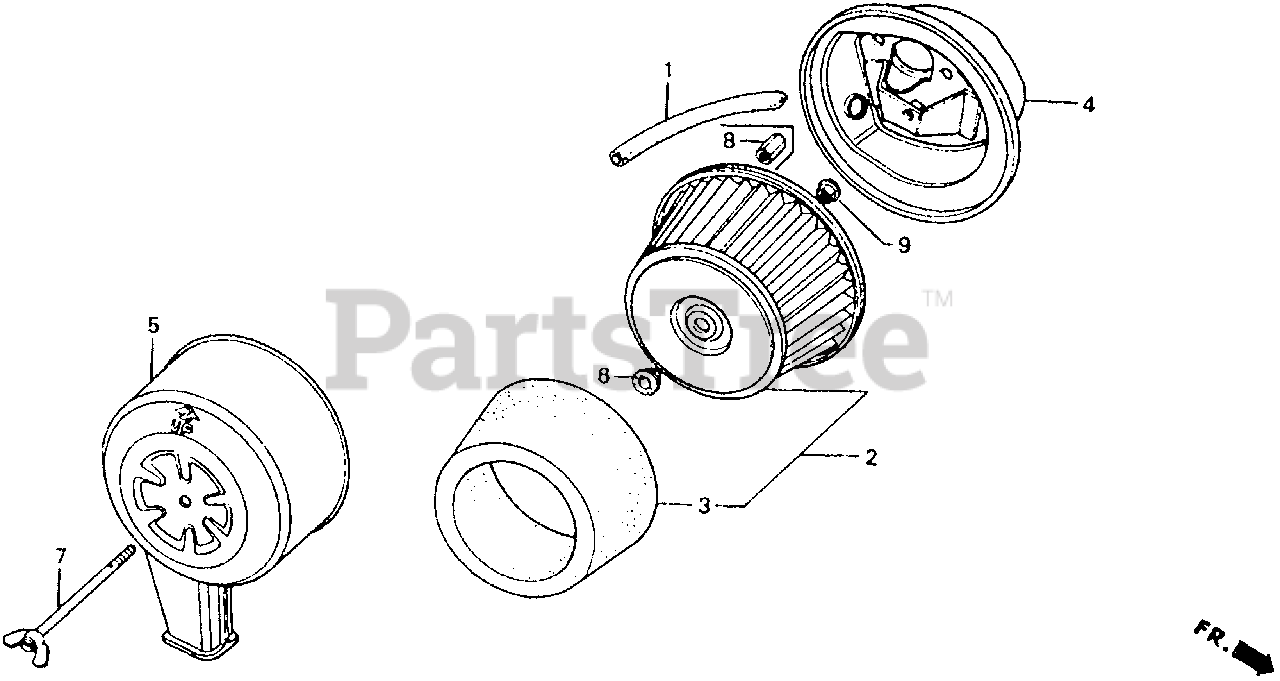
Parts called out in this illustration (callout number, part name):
1	TUBE, BREATHER
2	ELEMENT, AIR CLEANER
3	ELEMENT B, AIR CLEANER
4	HOUSING, AIR CLEANER (NOT AVAILABLE)
5	COVER, AIR CLEANER (NOT AVAILABLE)
6	GROMMET, AIR CLEANER
7	BOLT, AIR CLEANER COVER
8	NUT (6X15)
9	NUT, FLANGE (6MM)
